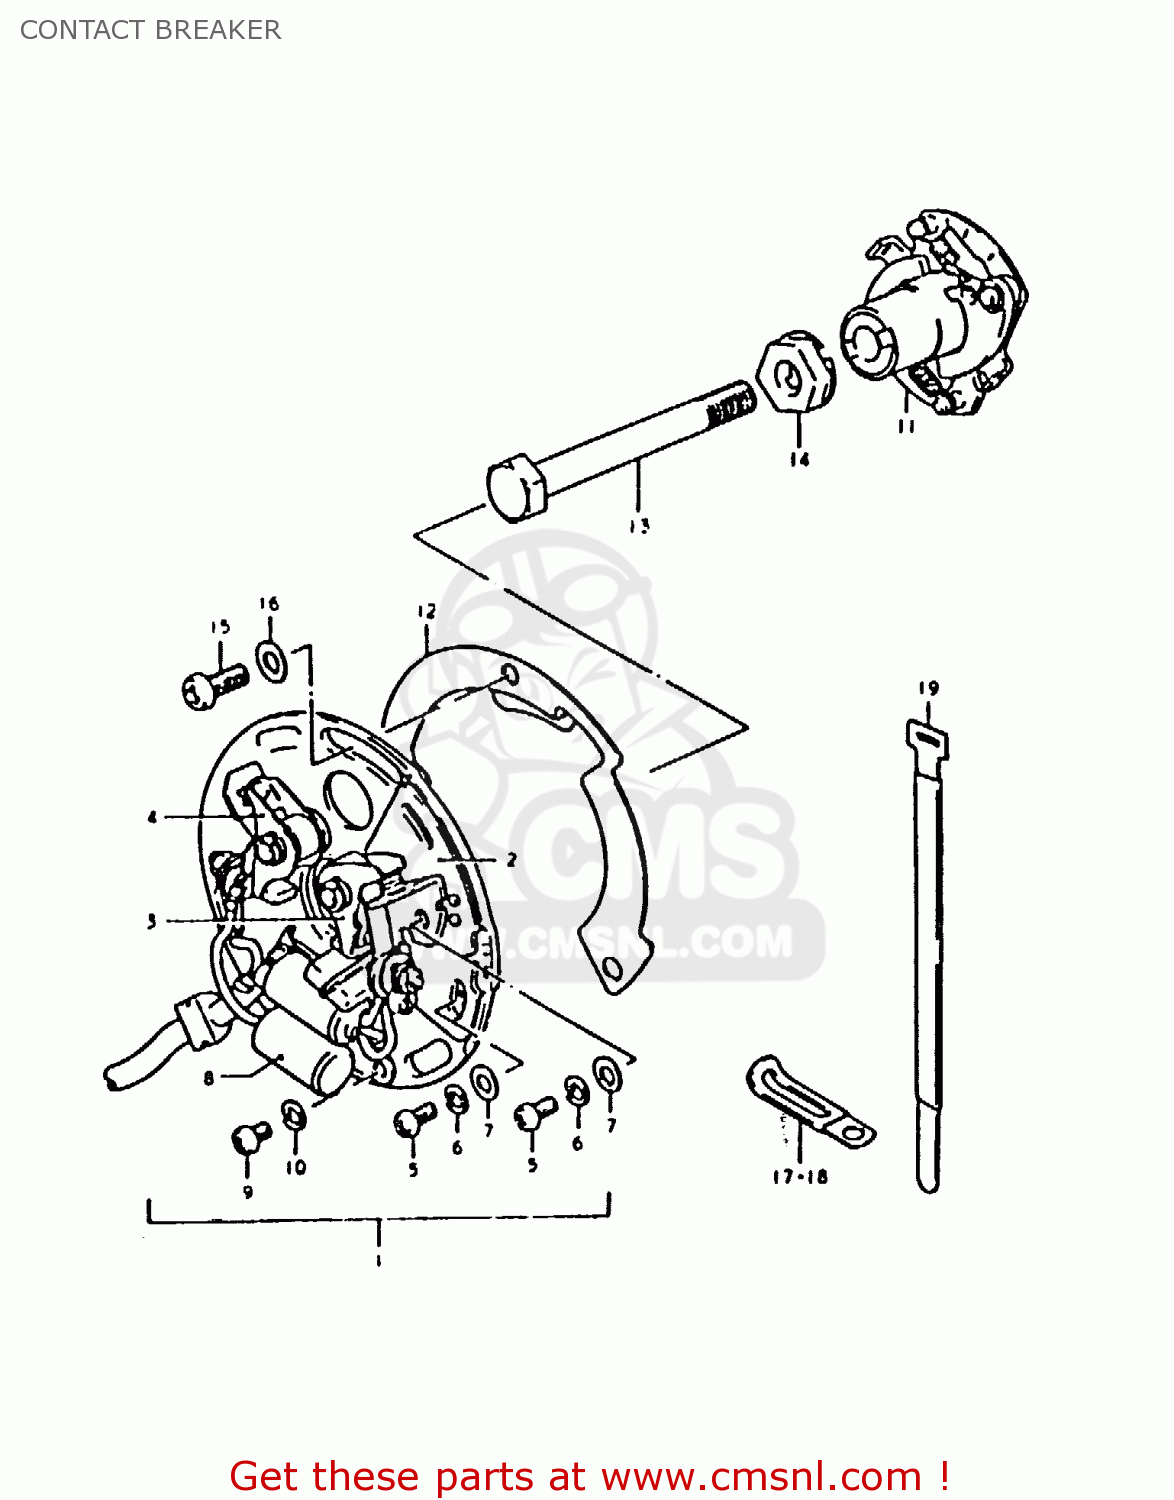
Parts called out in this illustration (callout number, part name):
1	BREAKER ASSEMBLY,CONTACT
2	PLATE,CONTACT POINT
3	POINT ASSY,R
4	POINT ASSY,L
5	SCREW(4X10)
6	LOCK WASHER
7	WASHER
8	CONDENSER
9	SCREW
10	LOCK WASHER
11	GOVERNOR ASSEMBLY
12	PLATE,IGNITION TIMING
13	BOLT
14	WASHER
15	SCREW(5X12)
16	WASHER 5MM
17	CLAMP L:35
18	CLAMP
19	CLAMP
